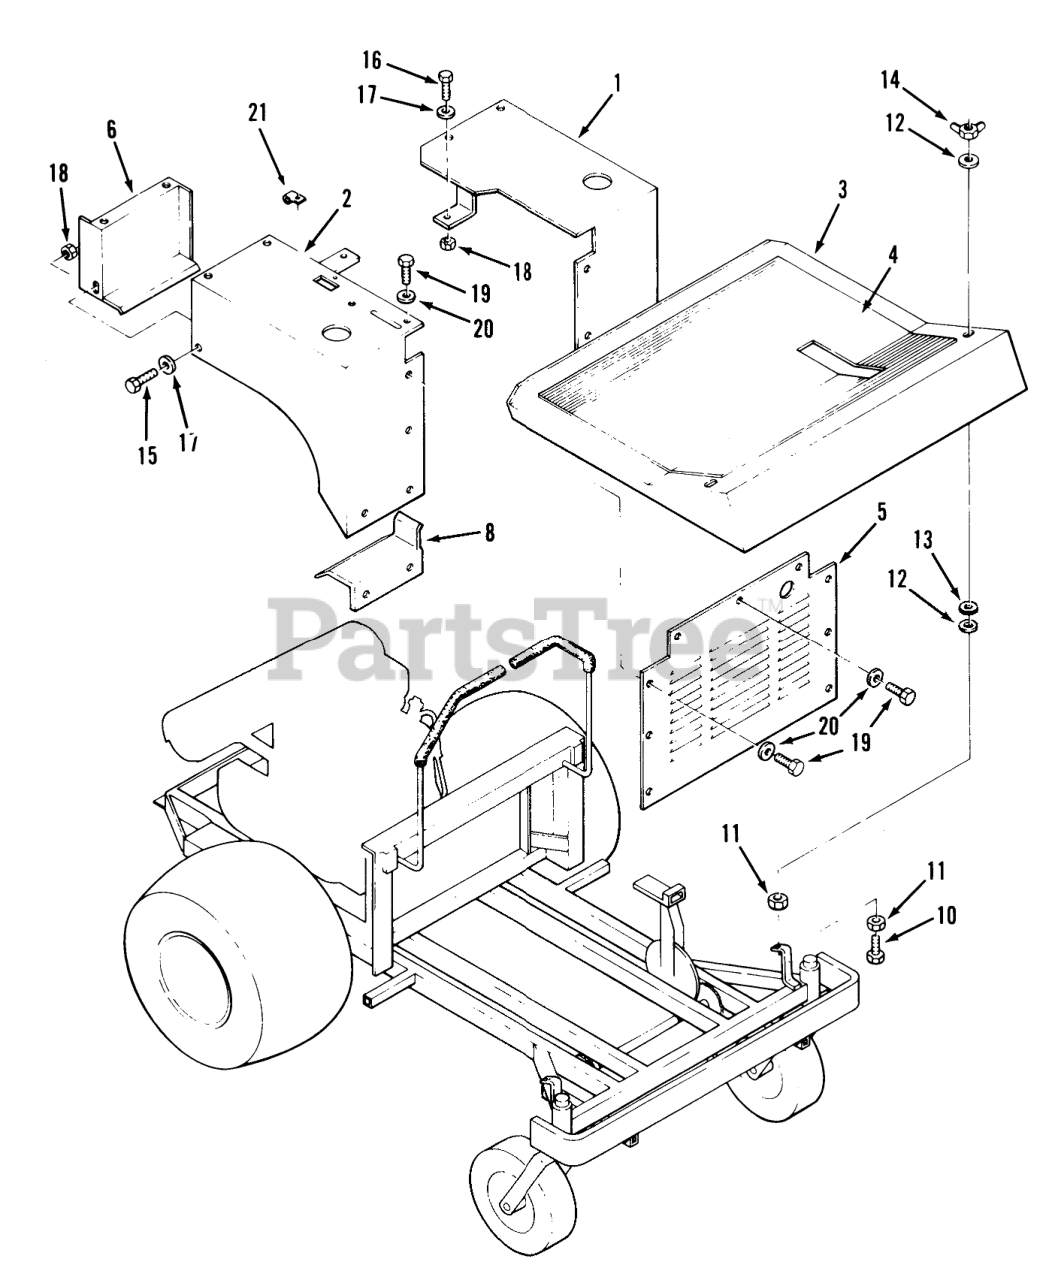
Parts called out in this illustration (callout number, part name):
1	Fender LH
2	FENDER WA RH R
3	Floor Pan
4	Black Carpet
5	Front Panel
6	Bracket-Fender Rear RH
8	Bracket-Fender Frt RH
10	SCREW-HH
11	NUT-HEX
12	Washer
13	WASHER
14	WING NUT
15	H H C S
16	Bolt
18	Nut
19	Bolt
20	WASHER
21	J-CLIP
